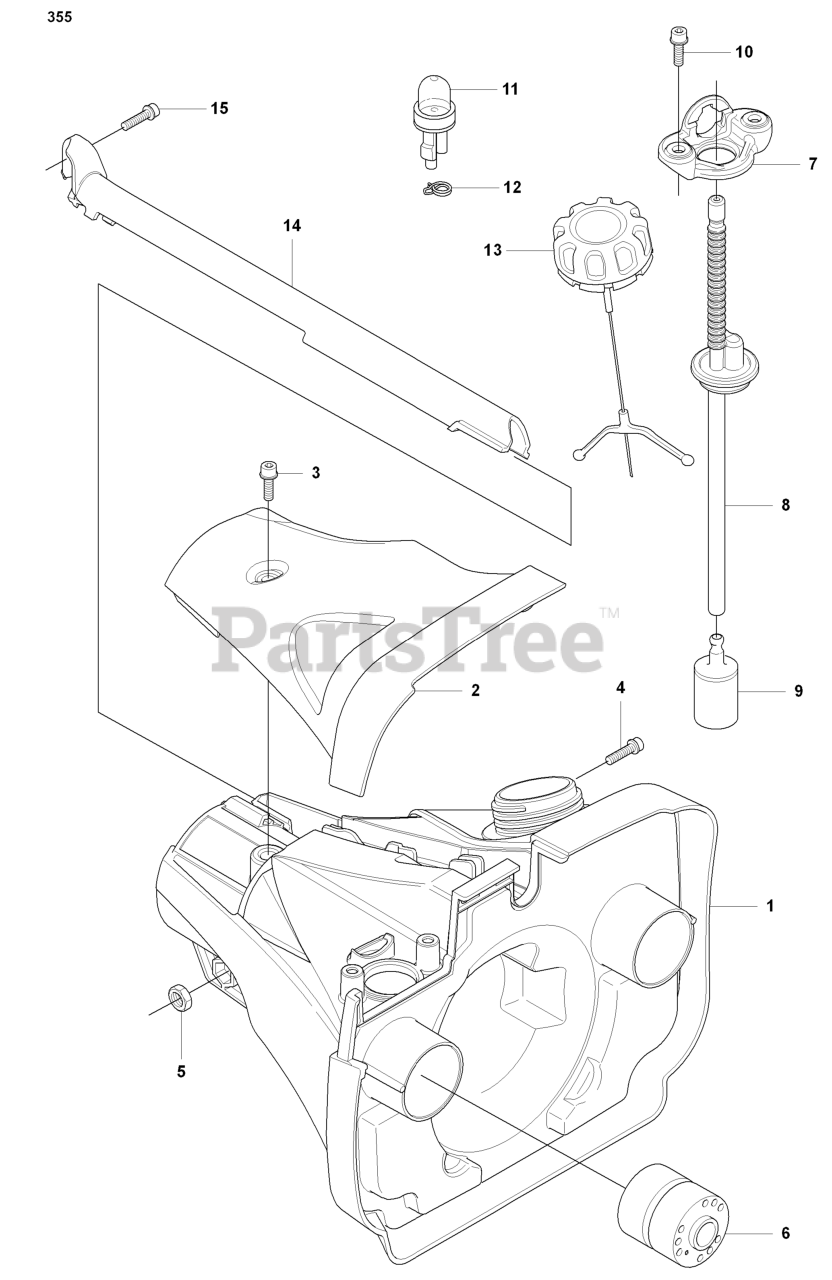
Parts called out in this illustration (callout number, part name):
2	COVER
3	SCREW IHSCFM
6	ANTIVIBE ELEMENT
9	RP FUEL FILTER
11	AIR PURGE BUBBLE
12	HOSE CLAMP
13	TANK CAP
14	WIRING PROTECTION
15	SCREW IHSCFM
